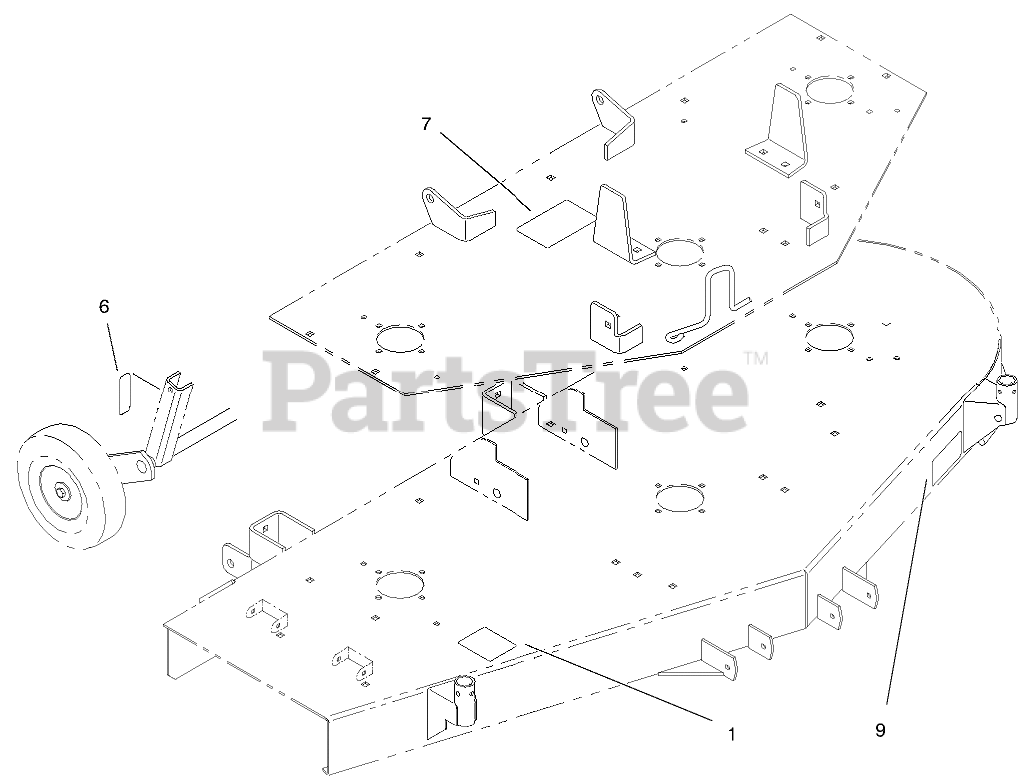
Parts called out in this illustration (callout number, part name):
1	DECAL-BELT ROUTING
6	Decal-Height Of Cut (Only On: 78395)
7	DECAL-BELT ROUTING
9	DECAL-ADJUSTMENT, WHEEL
